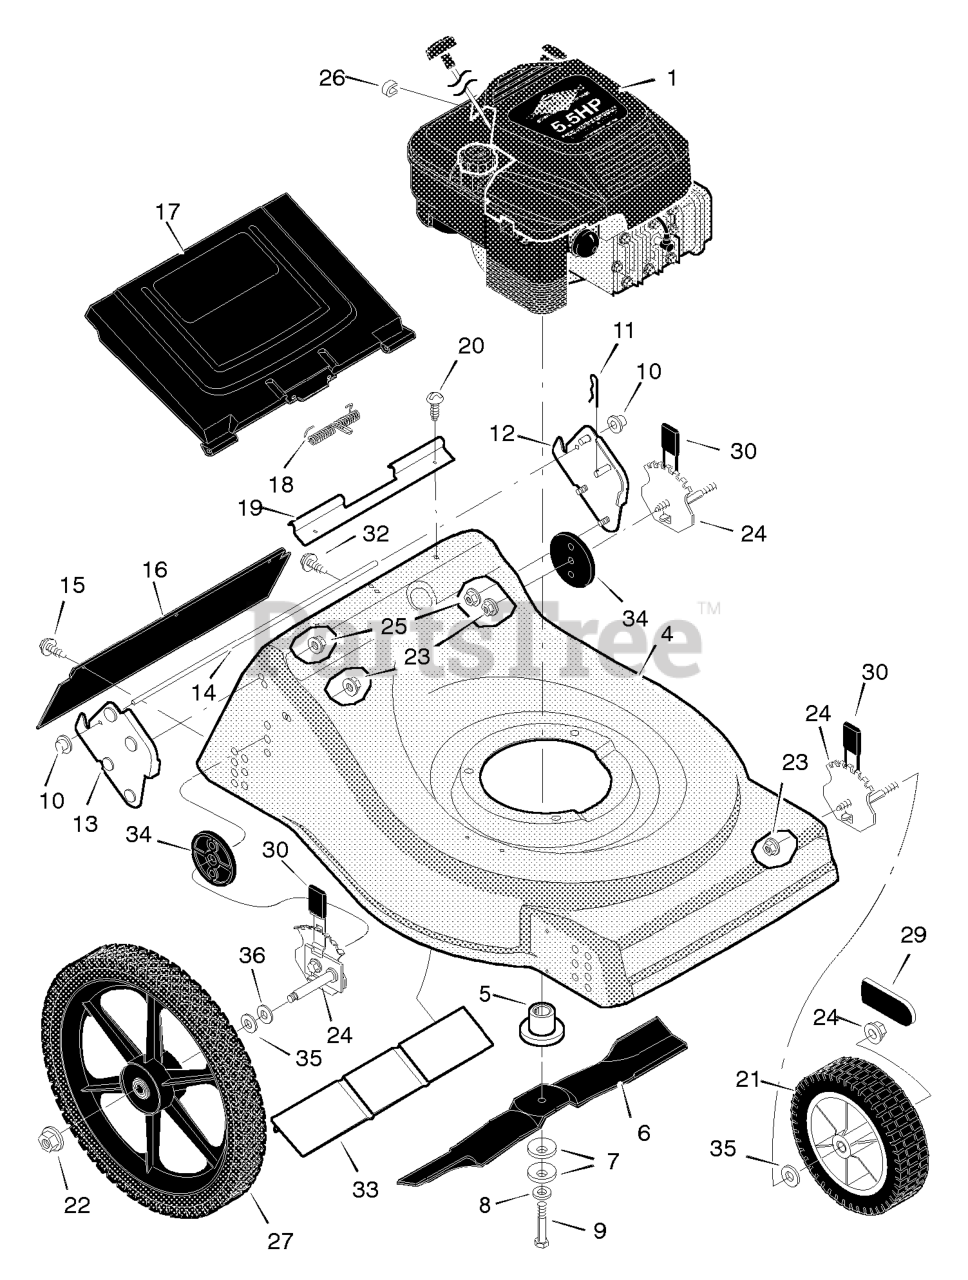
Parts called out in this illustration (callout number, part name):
1	Engine *
3	Bolt, Engine
4	Housing
5	Adapter, Blade
7	Washer, Belleville
9	Bolt, Hex
10	Push- On Cap
11	Pin, Hair
12	Bracket, Left Handle
13	Bracket, Right Handle
14	Rod, Door Pivot
16	Deflector, Rear
17	Door, Rear
18	Spring, Torsion
19	Spacer, Door
21	Wheel and Tire *
22	Nut, Flange
23	Nut, Flange
24	Height Adjuster
25	Nut, Flange
26	Stop, Rope
27	Wheel and Tire, Rear
28	Hub Cap
29	Hub Cap
